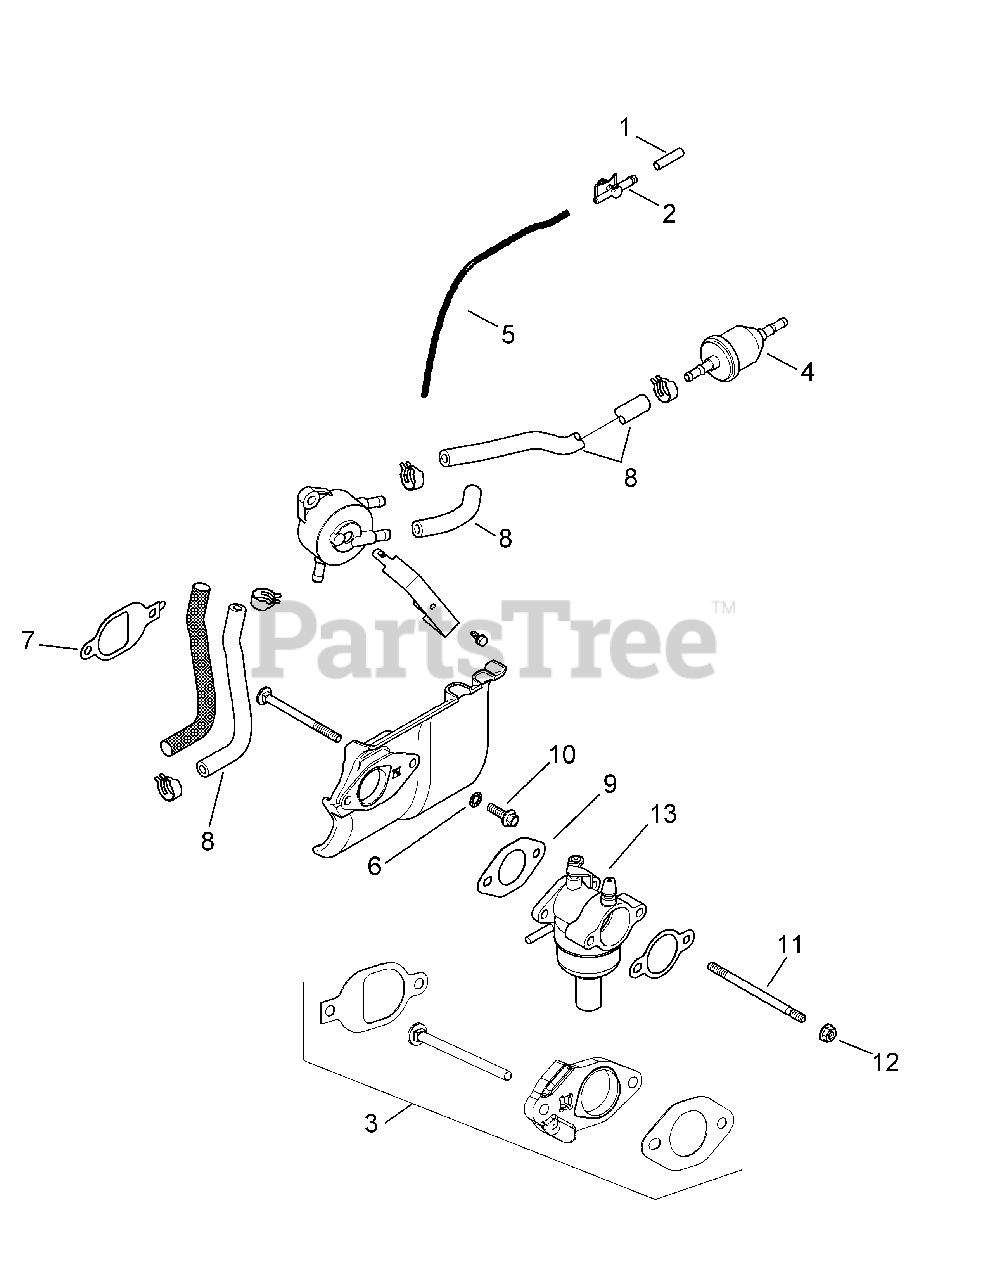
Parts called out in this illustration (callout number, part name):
2	Evaporative Connector
3	Carburetor Spacer Kit
5	Evaporative Hose
6	Int. Tooth Lock Washer, 1/4
7	Heat Deflector Gasket
9	Carburetor Gasket
10	Flange Screw, M6 X 1.0 X 20
12	Flange Nut, M6 X 1.0
13	Carburetor Kit
